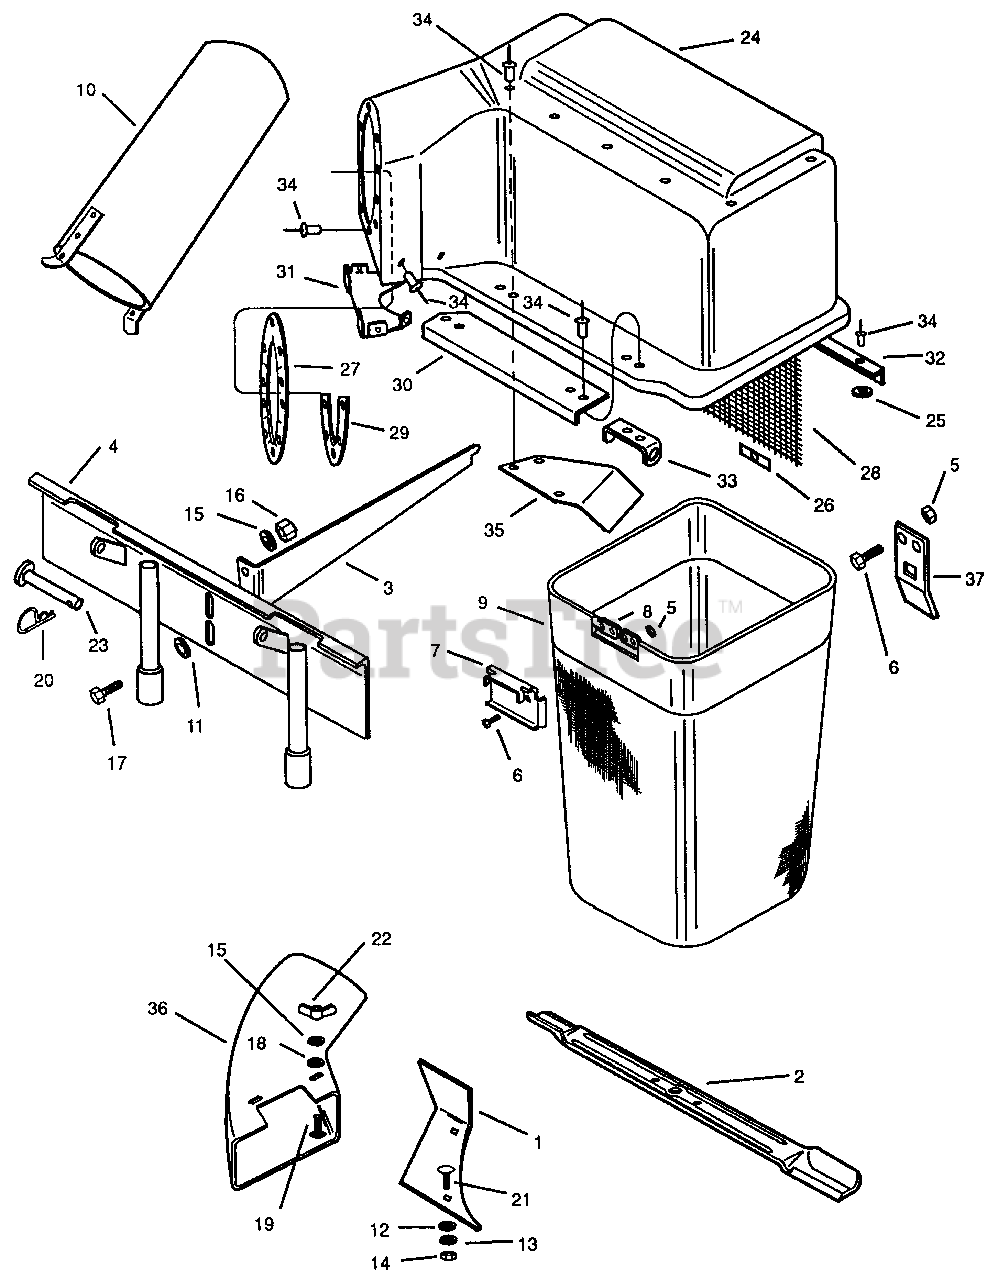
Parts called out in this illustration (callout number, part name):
1	Deflector-Chute
2	Blade-Mower
3	Bar-Cover Latch
4	Frame Assembly
5	Nut-Hex
6	Screw
7	Hanger-Bag
8	Frame-Bag
9	Grass Bag Assembly
10	Tube Assembly
11	Washer, Flat
12	Washer, Flat
13	Washer, Lock
14	Nut, Hex
15	Washer, Lock
16	Nut, Hex
17	Screw, Hex
18	Washer
19	Bolt, Carriage
20	Spring Clip
21	Bolt, Carriage
22	Wing Nut
23	Pin, Pivot
24	Cover & Decal Assembly
25	Washer
26	Strap-Screen Mounting
27	Gasket-Tube
28	Screen-Cover
29	Retainer-Gasket
30	Plate-Hinge
31	Plate-Corner
32	Angle-Cover
33	Hinge
34	Rivet
35	Deflector
36	Chute & Decal Assembly
37	Latch-Cover
